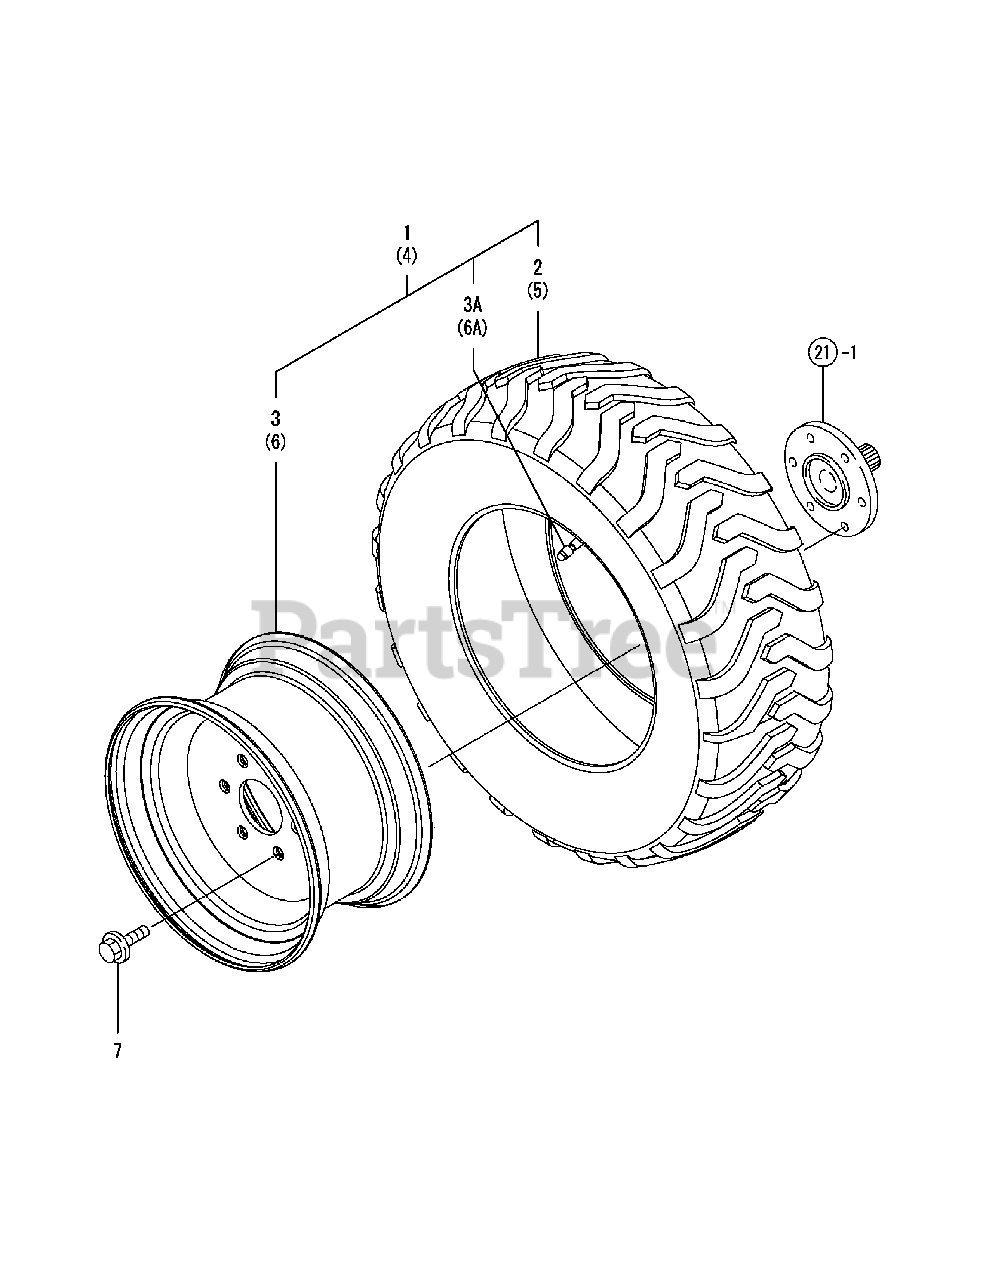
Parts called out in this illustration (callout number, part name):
1	R4 TIRE KIT, FRONT L
2	R4 TIRE 10-16.5
4	R4 TIRE KIT, FRONT R
5	R4 TIRE 10-16.5
